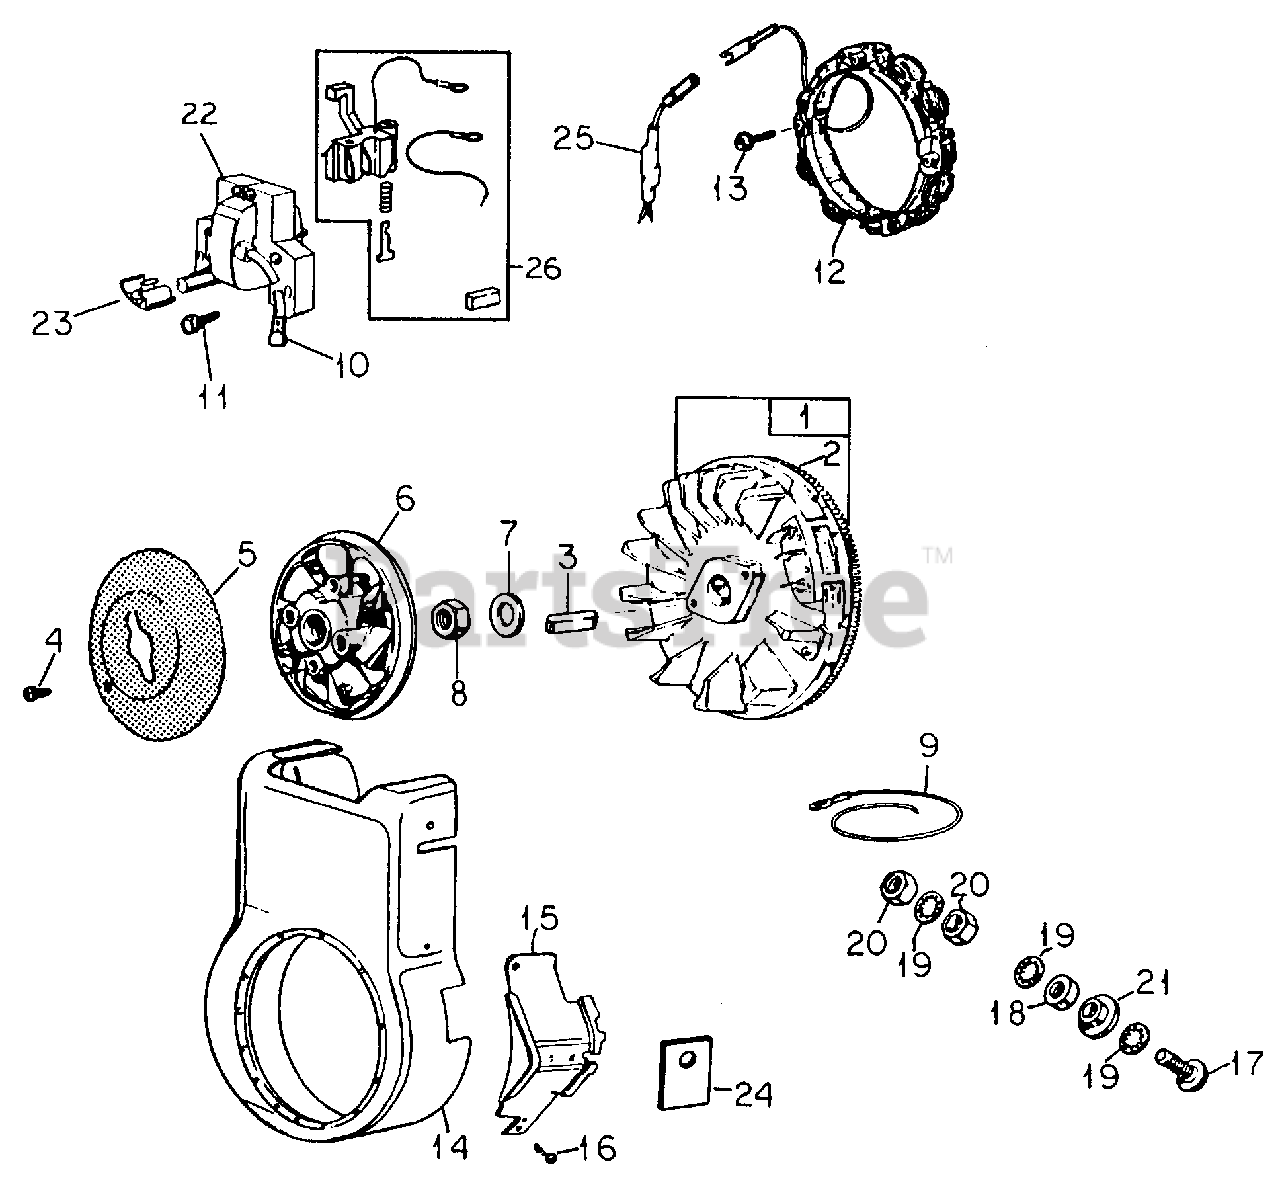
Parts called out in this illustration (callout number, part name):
1	Flywheel w/Ring Gear Assy, Magneto
2	Gear, Flywheel Ring
3	Key, Flywheel
4	Screw, Flywheel Screen
5	Screw, Flywheel
6	Fan, Booster
7	Washer, Spring
8	Nut, 5/8-NF Jam Type 5
9	Cable Assy, Ground
10	Terminal, Magneto Cable
11	Screw, Armature Mounting
12	Stator, Alternator
13	Screw, Stator Mounting
14	Housing, Blower
15	Cover, Starter Shield
16	Screw, Starter Shield
17	Screw, Terminal Mounting
18	Washer, Insulating
19	Washer, Lock
20	Nut, Terminal
21	Collar, Insulating
22	Armature Assy
23	Shield, Capsule
24	Retainer, Wire
25	Cable Assy, Alternator
26	Module, Magnetron Ignition
